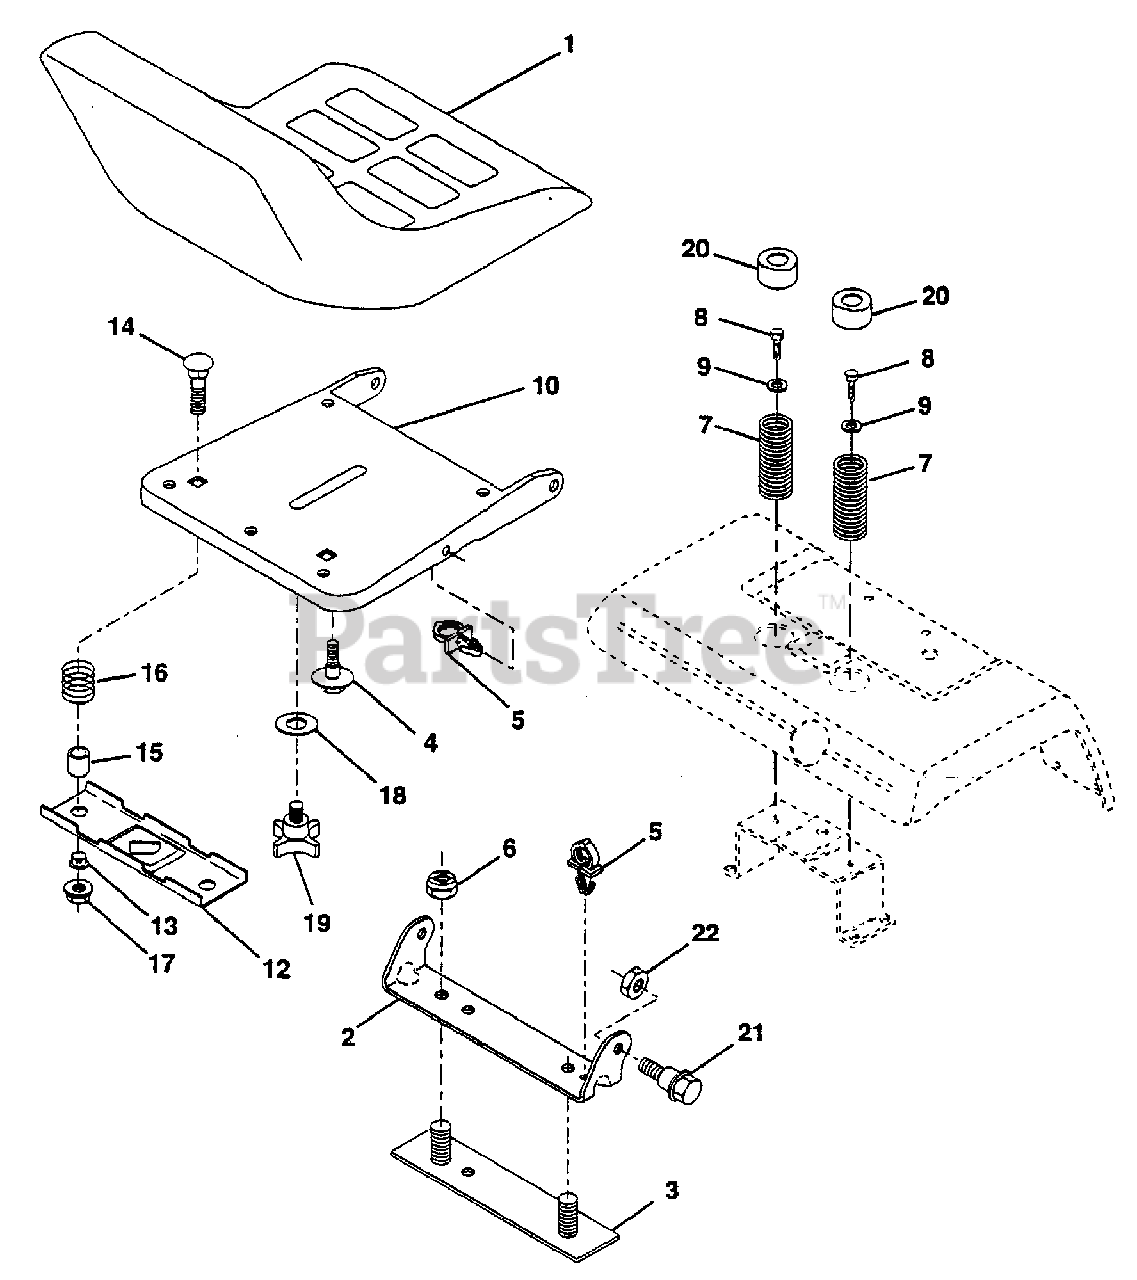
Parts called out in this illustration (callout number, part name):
1	Seat
2	Bracket, Pivot Seat
3	Strap, Fender
4	Bolt, Shoulder 5/16-18 X .62
5	Clip, Push In
6	Locknut 3/8-16 Unc
7	Spring, Seat Cprsn
8	Screw, Thdrol 5/16-18 X 1/2
9	Washer 13/32 X 1 X 14 Ga.
10	Pan, Seat
12	Bracket, Mounting Switch
13	Bushing, Snap
14	Bolt, Carriage 1/4-20 X 1-3/8
15	Spacer, Split
16	Spring, Cprsn
17	Nut, Lock 1/4 Lge Flg Gr. 5
18	Washer 17/32 X 1-3/16 X 12 Ga.
19	Knob, Seat 1/2-13 Unc
20	Cap, Spring Seat
21	Bolt, Shoulder 5/16-18 Unc
22	Nut, Crownlock 5/16-18 Unc
